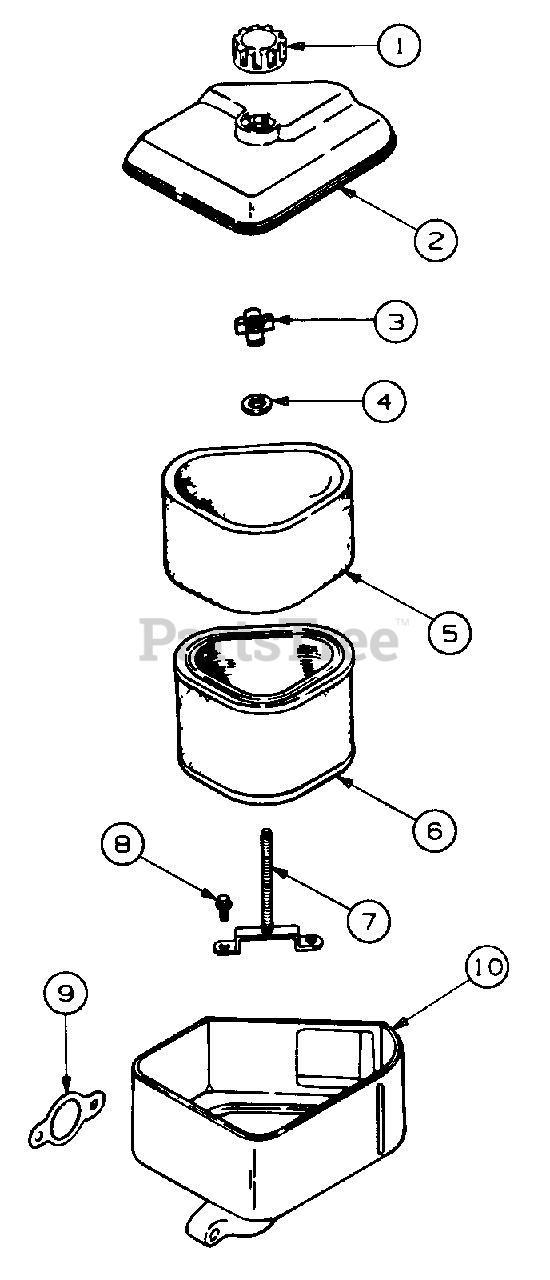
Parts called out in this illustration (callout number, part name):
1	Knob, Air Cleaner Cover
2	Cover, Air Cleaner
4	Washer, Plain, 1/4
5	Precleaner, Element
6	Element, Air Cleaner
7	Stud. Mtg Plate
8	Screw, Mtg Plate Stud
9	Gasket, Air Cleaner
10	Base, Air Cleaner
